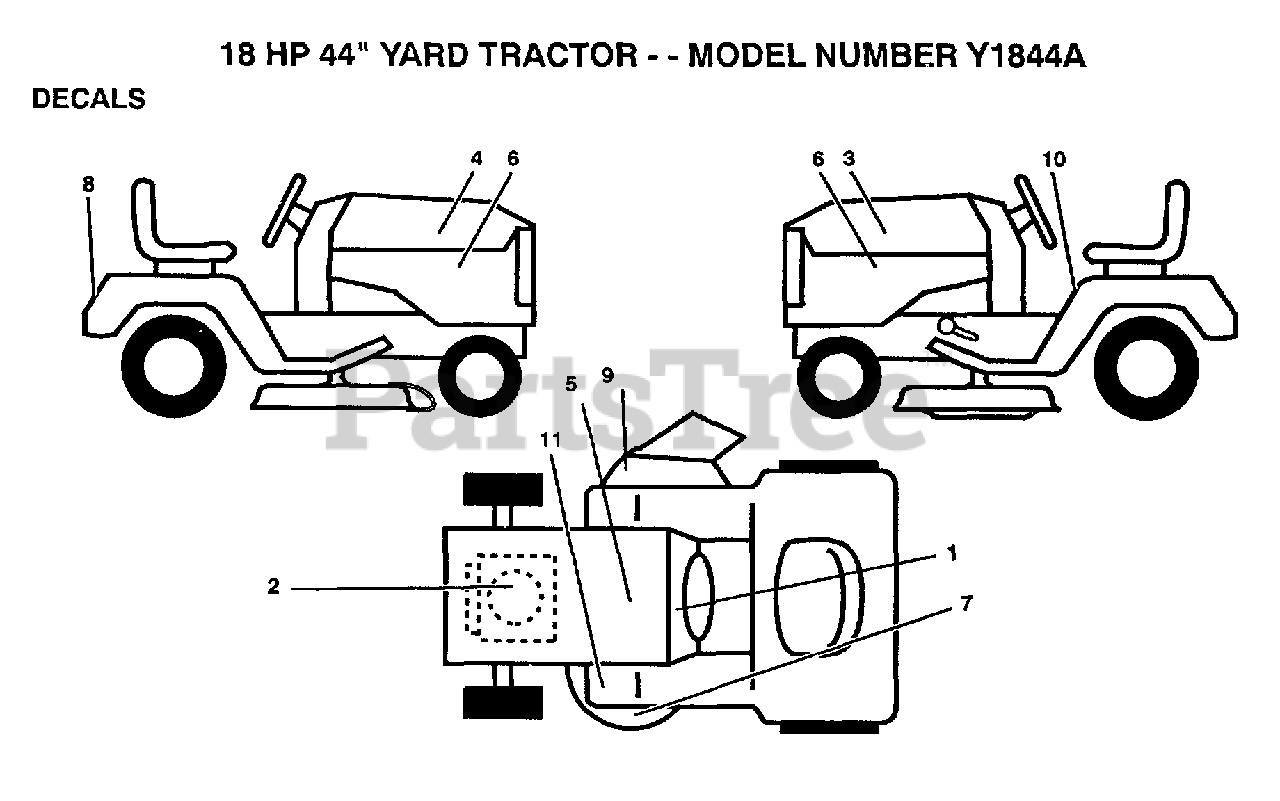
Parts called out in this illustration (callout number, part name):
2	"DECAL,HP ENGINE"
3	DECAL HOOD LH
5	DECAL
7	DECAL-INST YT
9	DECAL WARNING
10	DECAL CAUTION
11	DECAL T
